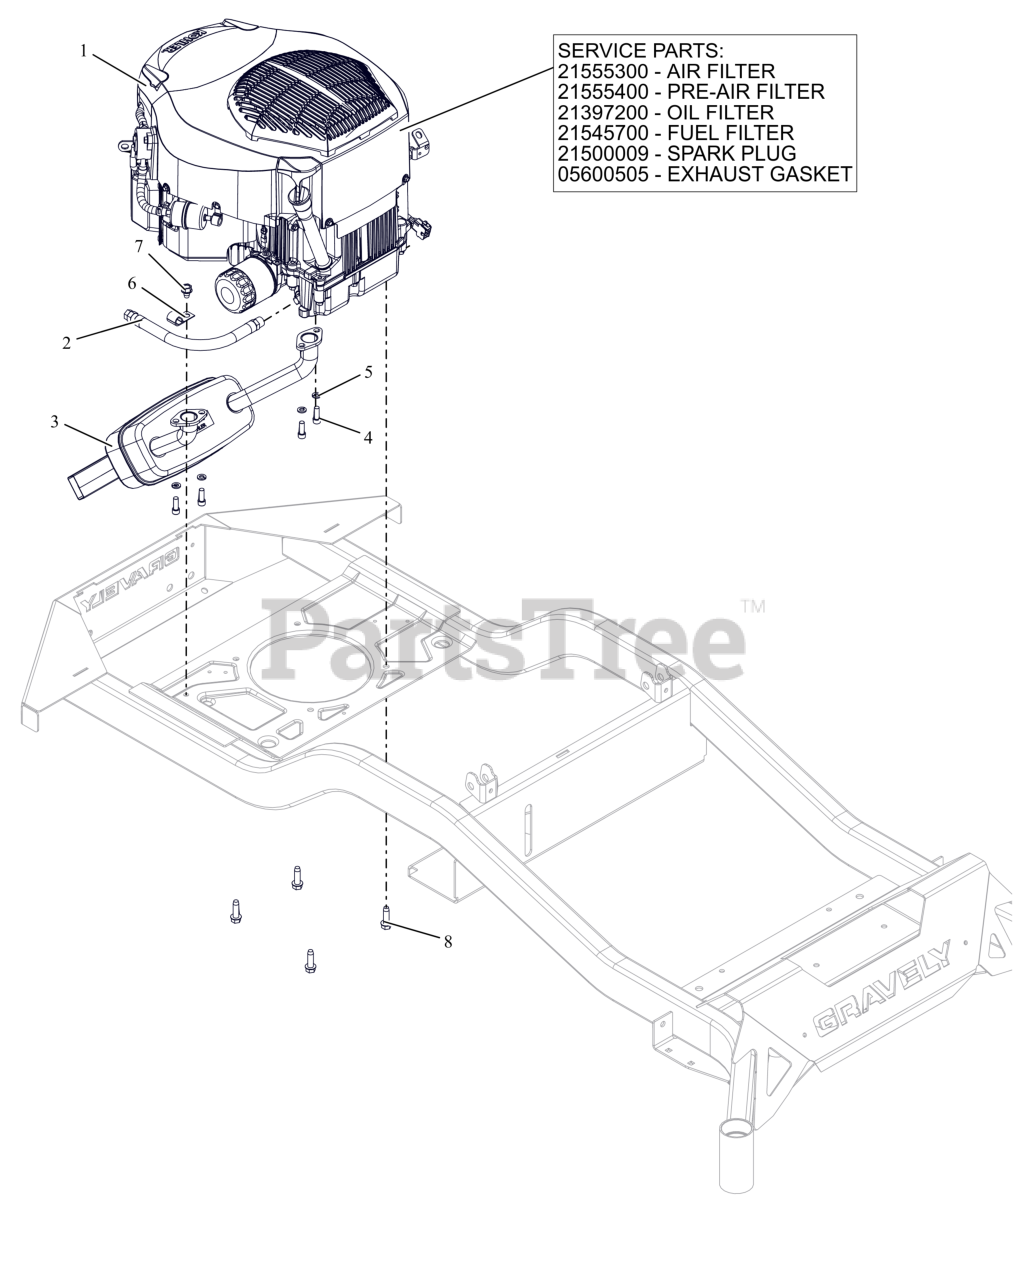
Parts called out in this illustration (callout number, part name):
1	ENGINE, KOHLER - KT740
1	AIR FILTER, KOHLER
1	PRE CLEANER, KOHLER
1	FILTER, OIL - KOH CV20
1	FILTER-FUEL KOHLER COURAGE PRO
1	PLUG, SPARK KOHLER
1	GASKET, MUFFLER KOHLER TWIN
2	HOSE, OIL DRAIN
3	MUFFLER, KOHLER
4	SCR, SKH .312-18X.875 GR8 ZCC
5	WSHR,LK-REG .312X.078 ZCC
7	SCR,TAP .375-16X.50 HWH TR ZCC
8	SCR,TAP .375-16X1.25HWH TR ZCC
